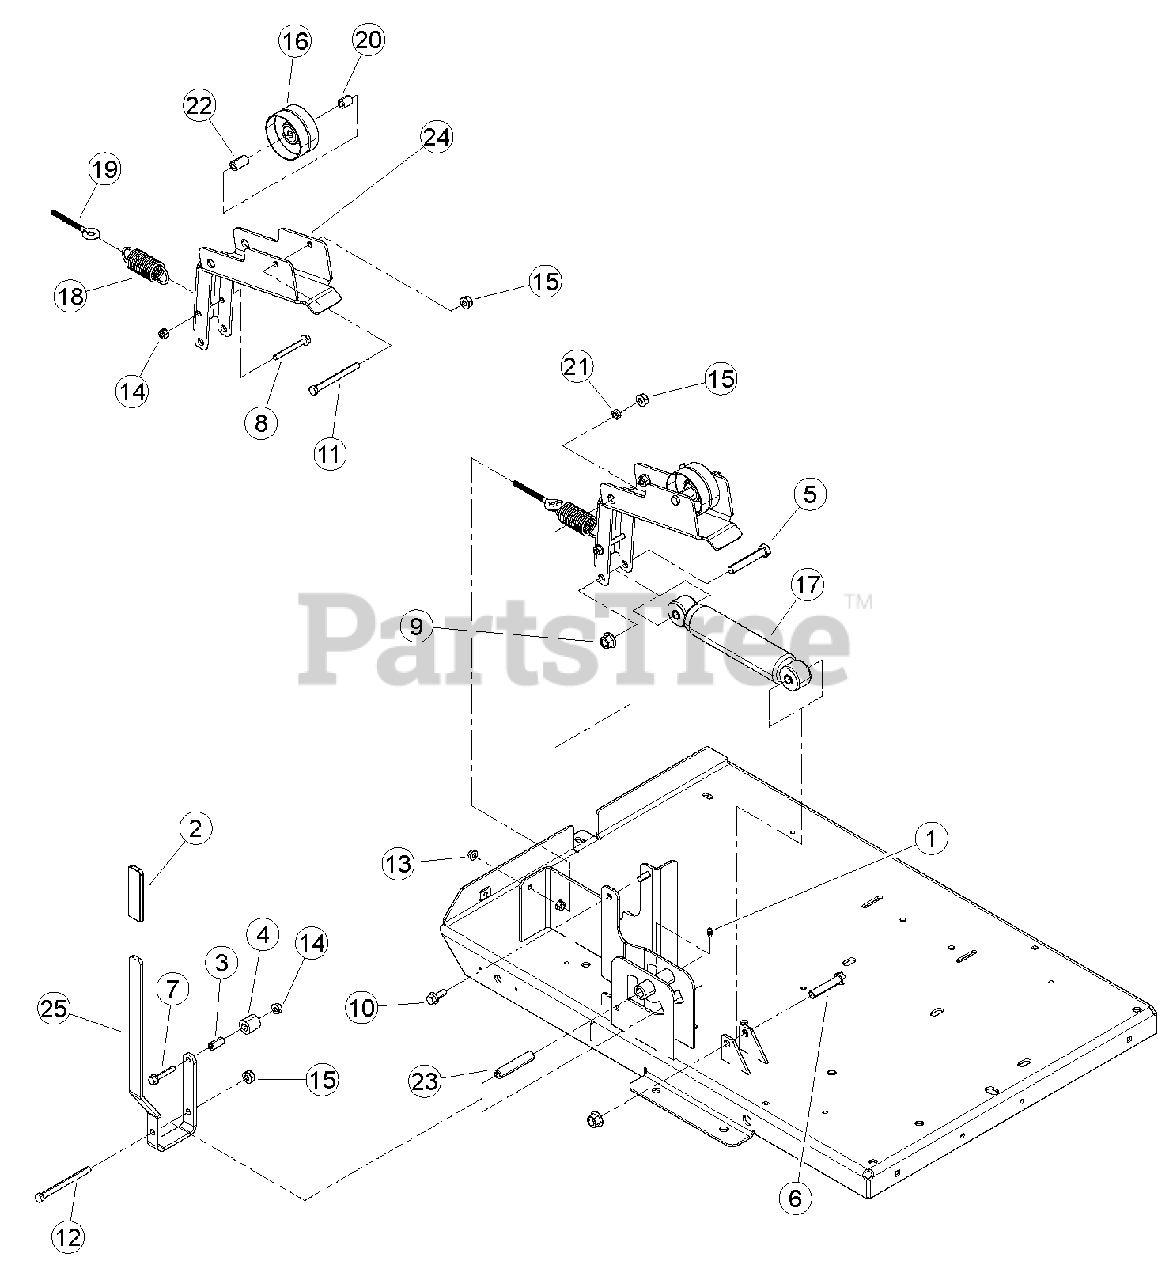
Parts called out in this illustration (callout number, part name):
1	FITTING, 1/4 SELF-TAP GREASE
2	GRIP, CLUTCH HANDLE
3	SPACER, 0.5 X 1.00
4	ROLLER, 0.5 X 1.00 X 1.00 NYLON
5	BOLT, 1/2 X 3 GR5 HEX HD ZP
6	BOLT, 1/2 X 2-1/2 GR5 HEX CAP ZP
7	BOLT, 5/16 X 1-3/4 FLANGE NC
8	BOLT, 5/16 X 2-3/4 FLANGE NC
9	NUT, 1/2-13 NYLOCK FLANGE
10	BOLT, 3/8 X 1 FLANGE NC
11	BOLT, 3/8 X 4" HHCS GR5 NC ZP
12	BOLT, 3/8 X 4-1/2" HHCS GR5 NC ZP
13	NUT, 5/16 SERRATED FLNG NC ZP
14	NUT, 5/16-18 NYLOCK-FLANGE
15	NUT, 3/8-16 NYLOCK FLANGE
16	PULLEY, 3-1/4 FLAT IDLER
17	ABSORBER, IDLER SHOCK
18	SPRING, 1.25 OD X 3.50 LG X .148 WD
19	BOLT, 5/16 X 3-5/8" EYE
20	SPACER TUBE, 3/4" LONG IDLER
21	SPACER, IDLER PIVOT
22	SPACER, IDLER
23	SPACER, .63 X 3.060
24	WELDMENT, IDLER BRACKET
25	LEVER, CHIPPER ENGAGEMENT
